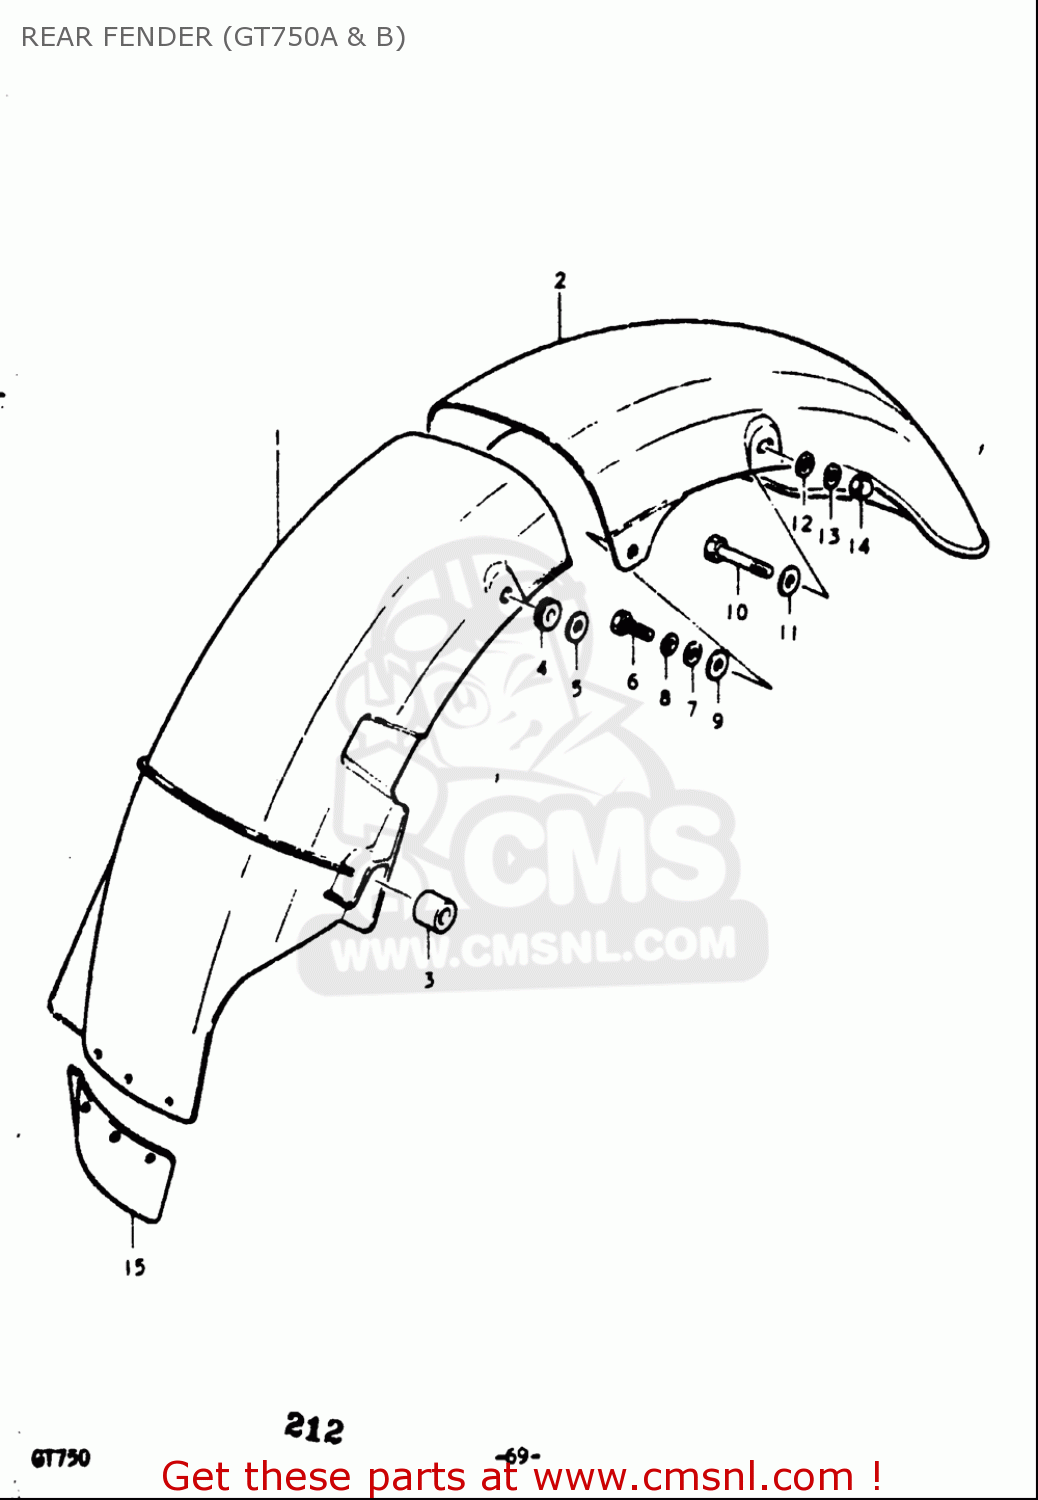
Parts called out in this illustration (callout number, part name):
1	BODY,RR FENDER FR
3	CUSHION
4	CUSHION
5	WASHER(6.5X18X1.6)
6	BOLT
7	WASHER
8	WASHER,LOCK
9	SPACER (6.5X20X5)
10	BOLT
11	WASHER (8.2X22X3.2)
12	WASHER
13	WASHER,LOCK
14	NUT
15	GUIDE,RR FENDER MUD
